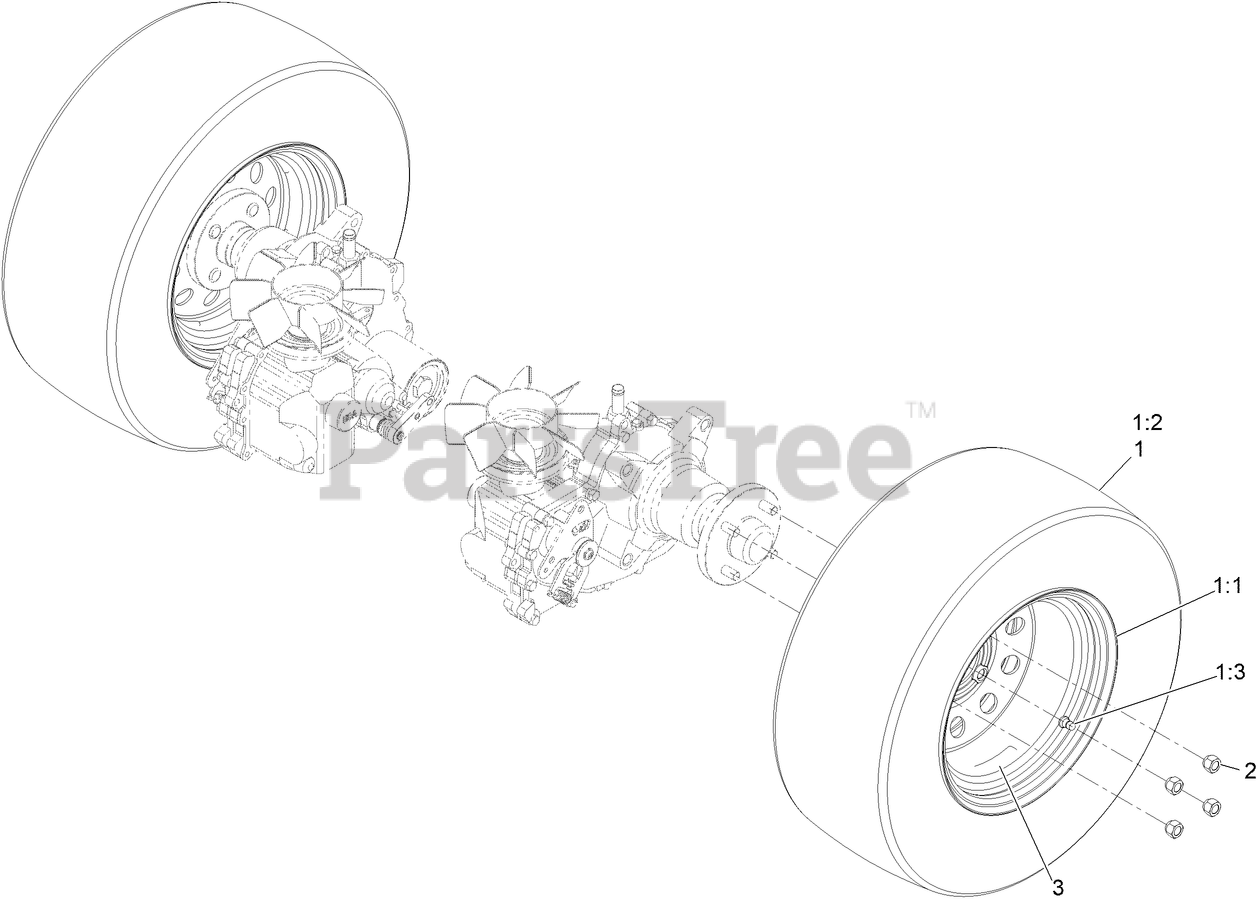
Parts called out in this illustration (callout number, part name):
1	ASM, Tire & Wheel
1:3	VALVE
2	NUT-LUG
3	DECAL-TORQUE, WHEEL NUT
